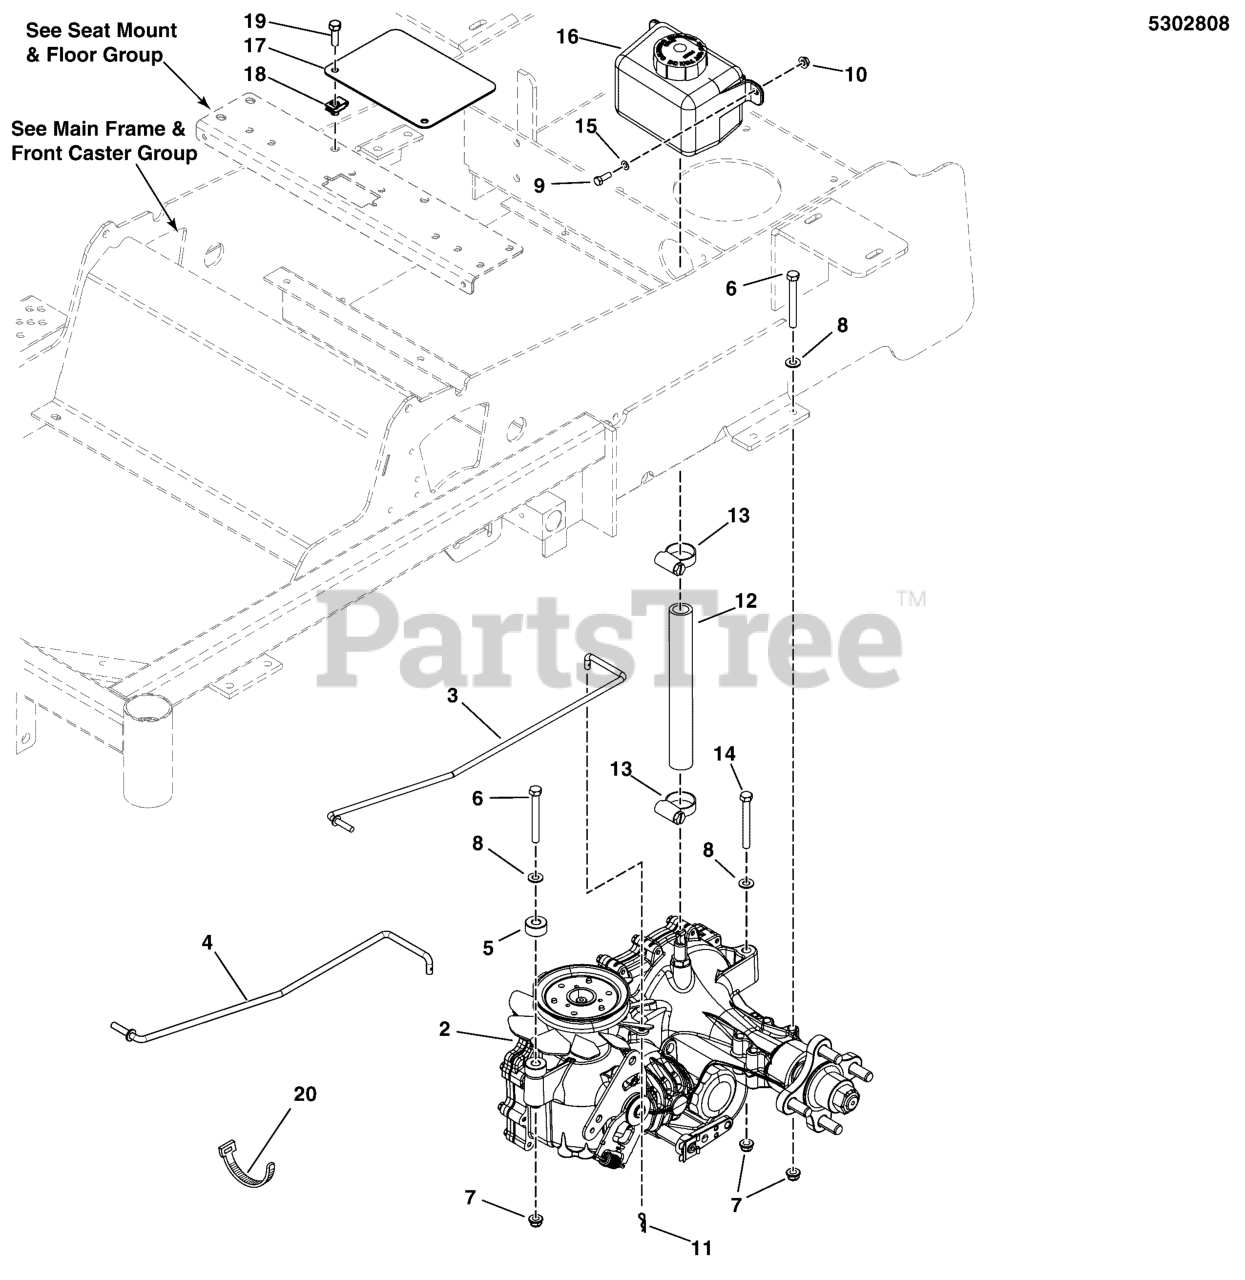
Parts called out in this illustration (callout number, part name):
2	TRANSAXLE, ZT3100, LH, ZL-KMEF-3L7C-1PLX
3	ROD, DUMP CONTROL, LH
4	ROD, DUMP CONTROL, RH
5	SPACER, .39 X .75 X .50, CZ
6	BOLT, 5/16-18 X 2-3/4, GD 5, YZ
7	NUT, 5/16-18 HEX NYLOCK FLANGE NUT
8	WASHER, 5/16" SAE
9	BOLT, 1/4"-20 X 3/4" GD5 YZ
10	NUT, 1/4-20 Hex Nylock Flange
11	PIN, HAIR, .0585 X 1-1/8, 1/4 EYE, YZ
12	HOSE, 1/2" PUSH-ON, 2.5" LONG
13	CLAMP, HOSE, .75 FREE DIA.
14	BOLT, 5/16-18 X 2-1/4" GD5 YZ
15	WASHER, 1/4 SAE
16	RESERVOIR, HYDRO OIL, 350 ML
17	PLATE, BELT GUARD - BLK
18	BODY CLIP, 5/16-18-7GA MATERIAL
19	BOLT, 5/16-18 X 1" GRD5 YZ
20	TIE, SELF-LOCKING, 12"
